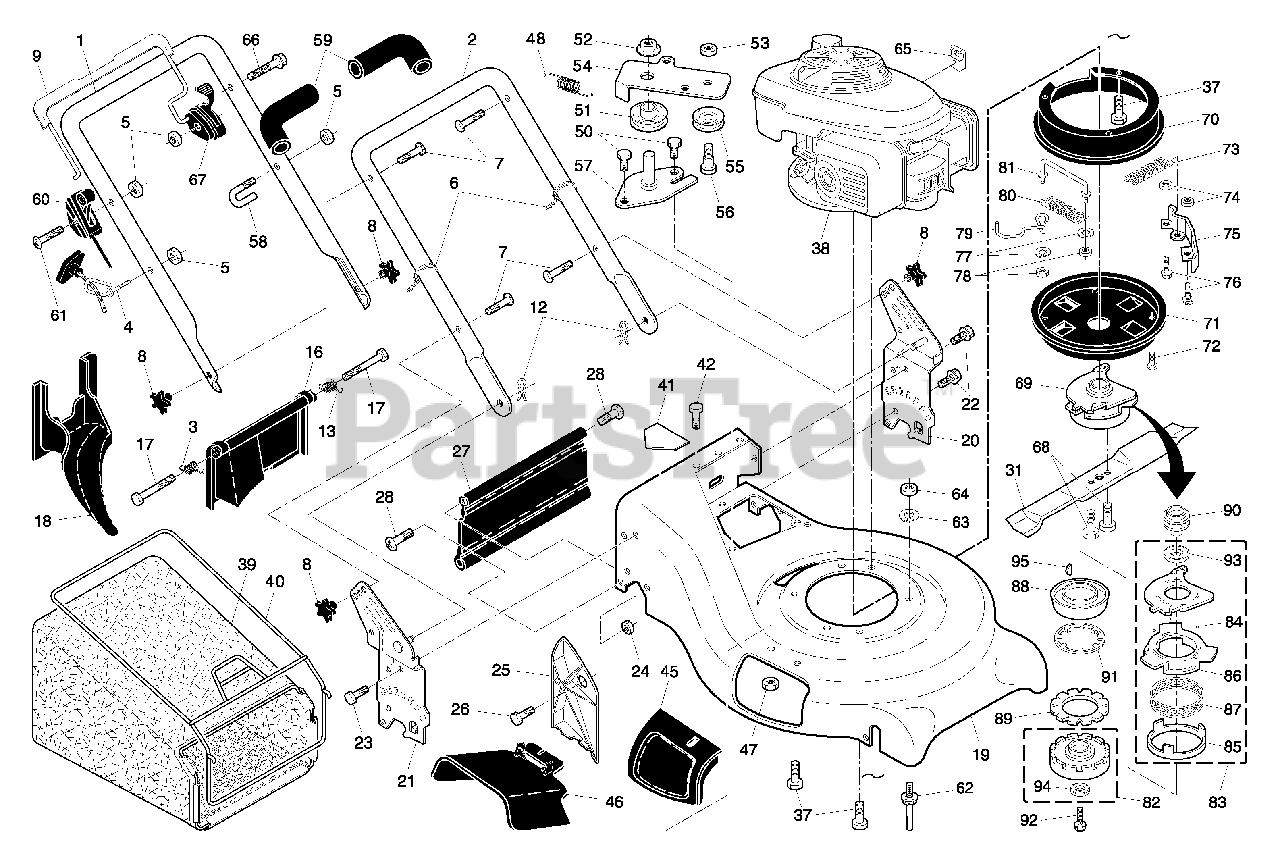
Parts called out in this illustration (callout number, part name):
1	Handle, Upper
2	Handle, Lower
3	Spring, Rear Door, RH
4	Guide, Rope, Side
5	Nut, Hex Lockwasher Insert 1/4-20
6	Wire, Tie
7	Bolt, Handle 5/16-18 x 1.75
8	Knob, Handle
9	Bar, Control, Auto-Walk
10	Bolt, Carriage
11	Nut, Hex, Centerlock 5/16-18 UNC
12	Cotter, Hairpin
13	Spring, Rear Door, LH
16	Rear Door Assembly
17	Bolt, Rear Door
18	Plug, Mulcher
19	Kit, Housing
20	Handle Bracket Assembly, LH
21	Handle Bracket Assembly, RH
22	Screw, Hex Washer Head
23	Bolt, Hex Head 5/16-18 x 5/8
24	Nut, Hex, with Lock Washer Insert 5/16-18
25	Baffl e, Side
26	Screw 12 x 5/8
27	Skirt, Rear
28	Screw, Hinge 1/4-20 x 1.25
31	Blade, 21"
37	Bolt, Engine
39	Grassbag
40	Frame, Grassbag
41	Danger Decal
45	Mulcher Door Assembly
46	Defl ector, Discharge
48	Spring, Return
51	Pulley Assembly, V-Groove
52	Flange Nut
53	Locknut
54	Idler Arm
55	Idler Pulley
56	Shoulder Bolt
57	Bracket Assembly
59	Grip, Handle, Foam, Smooth (one side)
60	Throttle / Engine Control
61	Screw, Hex Head 1/4-20 x 2-1/8
62	Belt Guide, Stud
63	Washer, Lock 3/8
64	Nut, Hex 3/8-16
65	Bracket, Throttle
66	Screw, Hex Washer Head 1/4-20 x 1/2
67	Blade Brake / Clutch Control
68	Bolt, Hex Head
69	Blade Brake / Clutch
70	Belt Cover, Upper
71	Belt Cover, Lower
72	Screw, Tapping, Hex Washer Head #10-24
74	Nut, Hex, Centerlock, Zinc Plated 1/4-20
75	Brake, Clutch
76	Bolt, Hex Cap Head 1/4-20 x 5/8
77	Washer, Flat
78	Nut, Hex 3/8-16
79	Belt Keeper
81	Link, Torque
82	Holder Assembly, Blade
83	Plate Assembly, Ball Control
84	Ball, Steel
85	Plate, Spring Hook
86	Plate, Brake
87	Spring, Ball Plate
88	Disk, Drive
89	Disk, Driven
90	Pulley, Drive
91	Spring, Clutch
92	Bolt, Flange (10 x 24)
93	Bearing, Radial Ball (6006)
94	Bearing, Radial Ball (6204)
95	Key, Woodruff (16 x 15)
